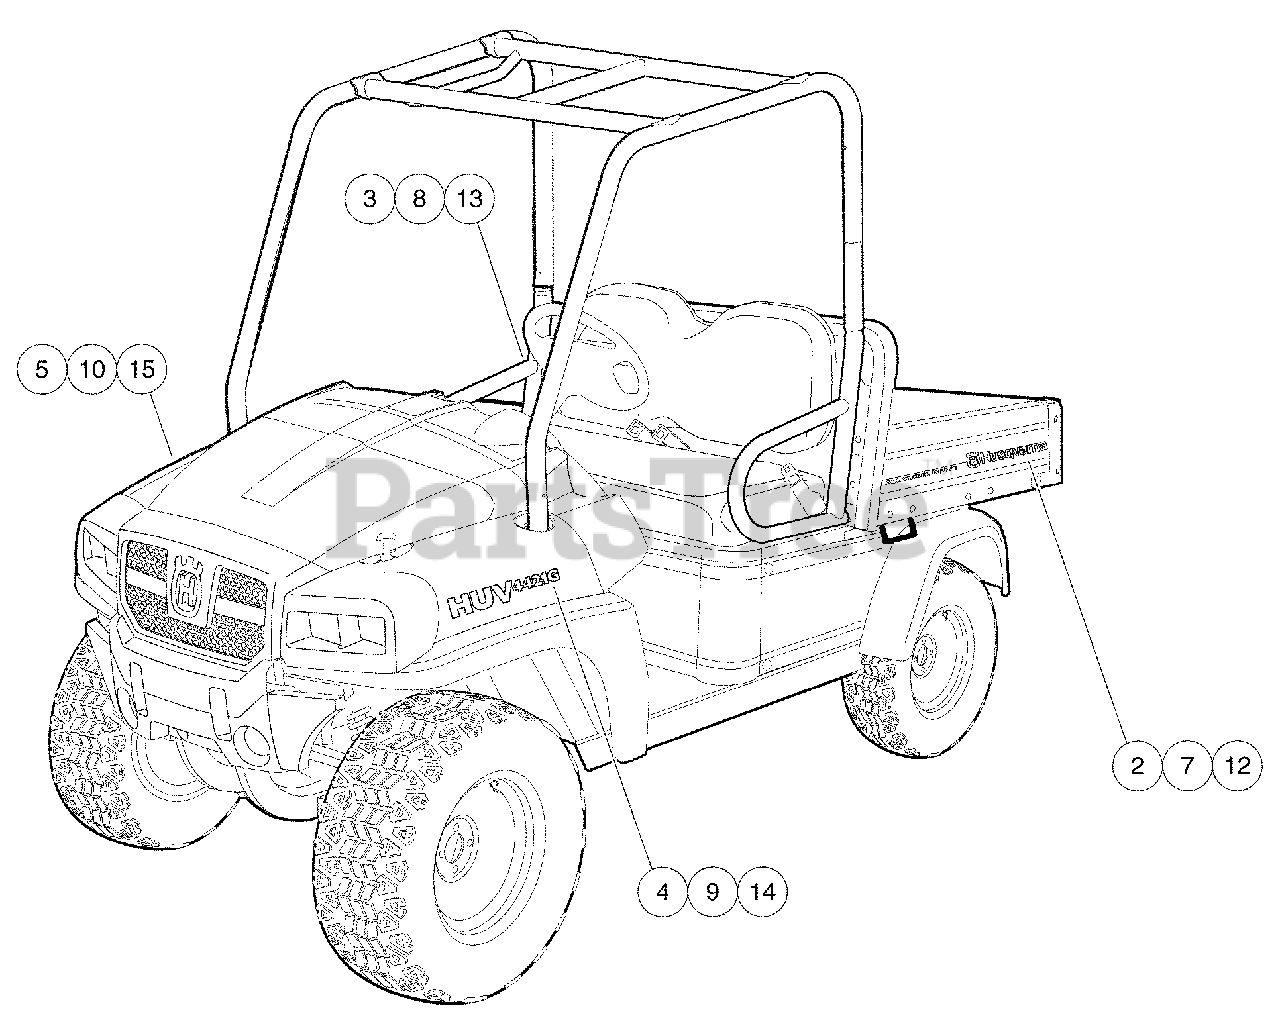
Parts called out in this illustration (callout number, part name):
1	Instl, Decal, Huv4421g,moff
2	Decal, Bed, Huv, Moff, Ds
3	Decal, Bed, Huv, Moff, Ps
4	Decal, Bct2200s, Driver-Side, Camo.
5	Decal, Bct2200s, Passenger-Side, Camo
7	Decal, Bed, Huv, Orange, Ds
8	Decal, Bed, Huv, Orange, Ps
9	Decal, Huv 4421g, Orange, Ds.
10	Decal, Huv 4421g, Orange, Ps
11	Instl,decal,huv4421g,olv Grn
12	Decal, Bed, Huv, Olv Grn, Ds
13	Decal, Bed, Huv, Olv Grn, Ps
14	Decal, Huv 4421g, Olv Grn, Ds.
15	Decal, Huv 4421g, Olv Grn, Ps
